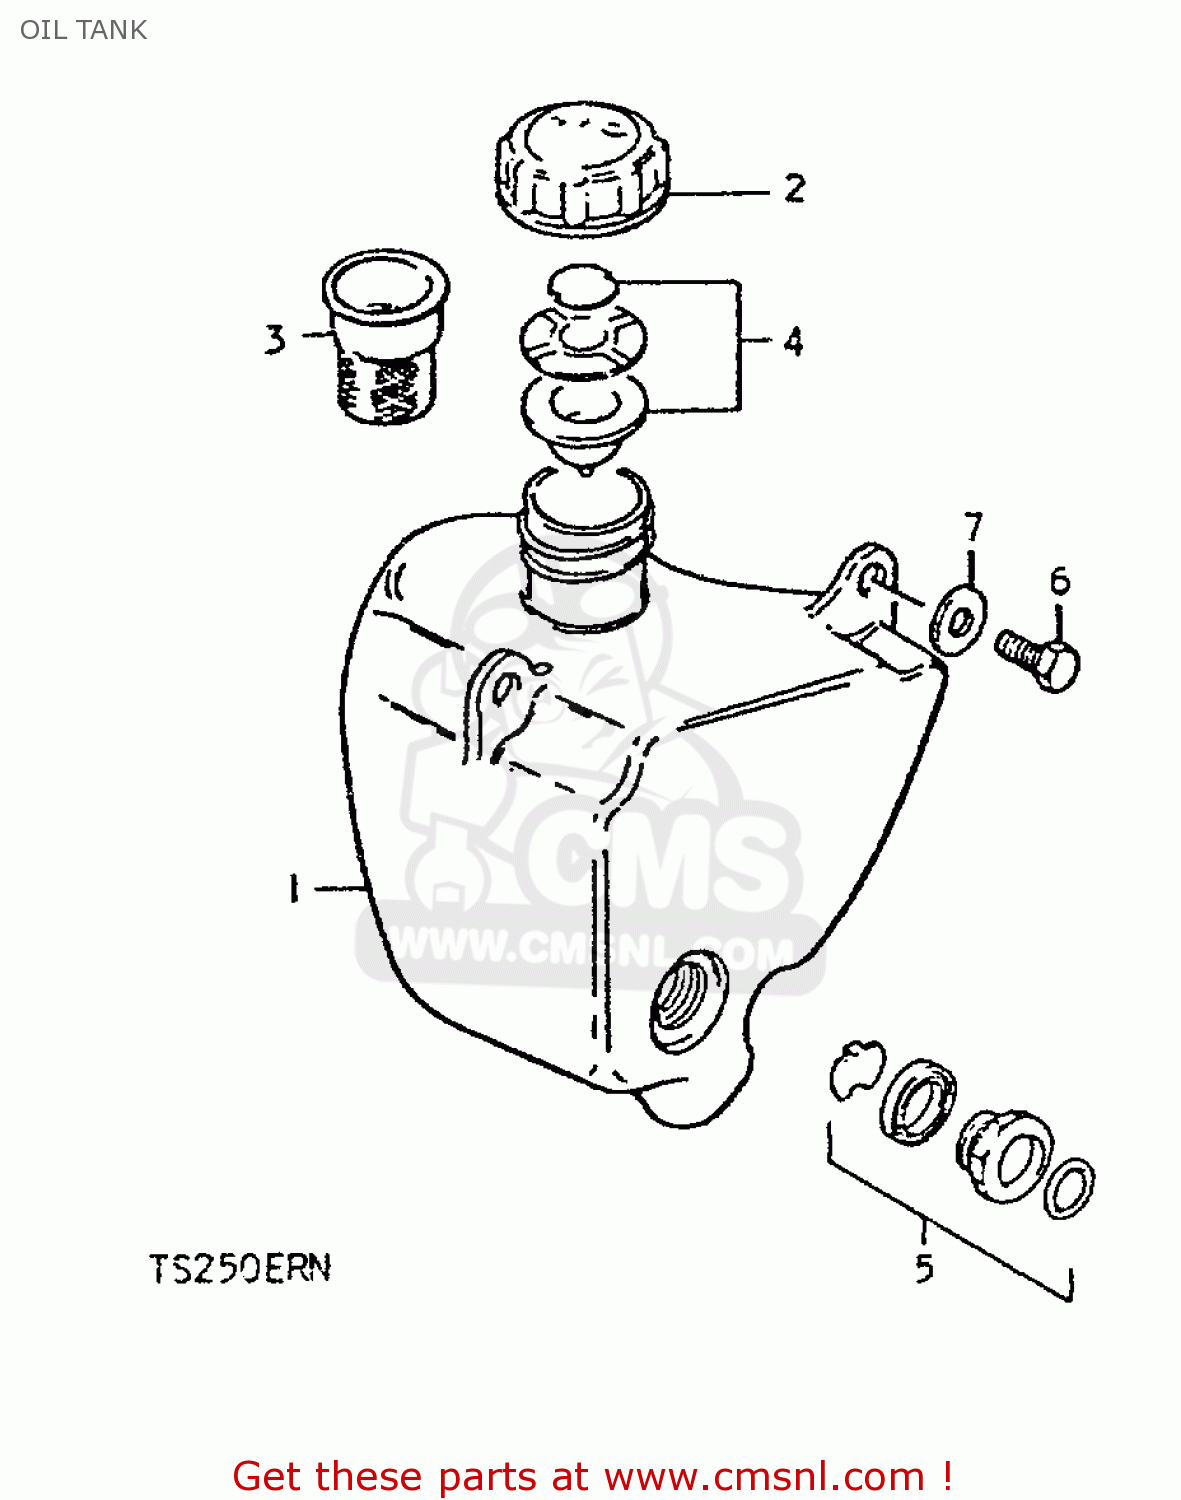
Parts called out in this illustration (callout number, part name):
1	TANK,OIL
2	CAP,OIL TANK
3	FILTER,OIL TANK INLET
4	GASKET SET (NAS)
5	LENS SET,OIL LEVEL
6	BOLT, UPPER
7	WASHER
